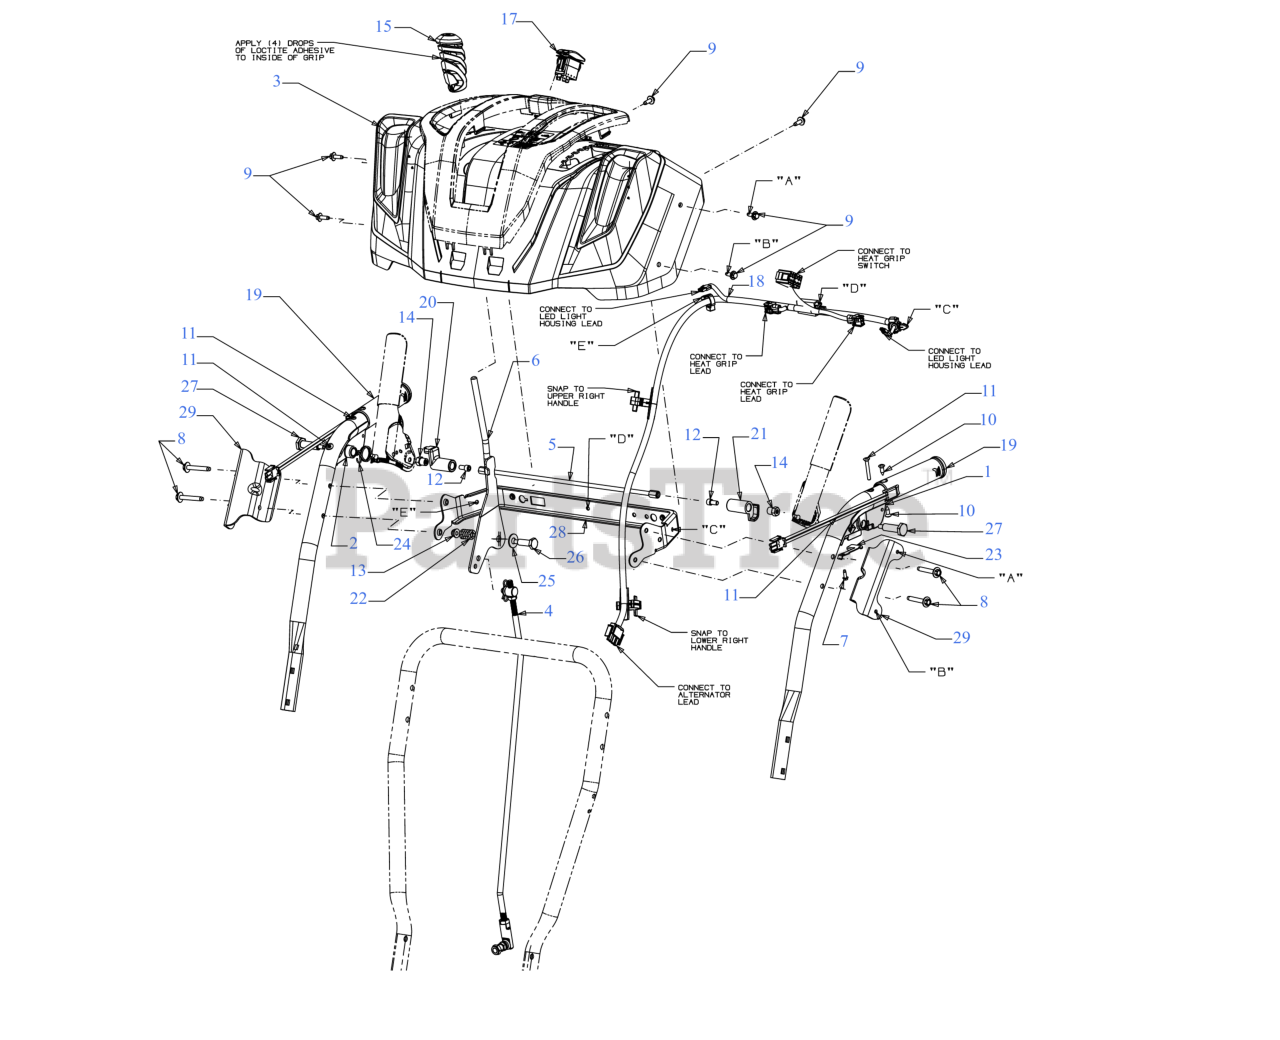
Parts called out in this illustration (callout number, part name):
1	CLUTCH LOCK HANDLE ASSEMBLY (LH)
2	CLUTCH LOCK HANDLE ASSEMBLY (RH)
4	SHIFT ROD ASSEMBLY
6	SPEED SHIFT CONTROL (POWDER BLACK)
7	SCREW #8-16 x .50
8	SCREW 1/4-20 x 1.625
9	SCREW M6-1 x .625
10	SCREW-AB #12-24 x .625
11	SCREW #10-24 x 1.375
12	SCREW 1/4-20 x .50
13	FLANGE LOCK NUT
14	HEX NUT W/PATCH
15	PTO HANDLE GRIP .355 ID
17	HEATED GRIP SWITCH
18	HARNESS (TWO HEADLIGHT)
19	HEATED GRIP
21	CLUTCH LOCK CAM
22	COMPRESSION SPRING
23	CLUTCH SPRING
24	TORSION SPRING
25	FLAT WASHER .40X.88X.060
26	SHOULDER SCREW
27	SHOULDER SCREW .437 x 1.345 1/4-20
28	HANDLE SUPPORT BRACKET (POWDER BLACK)
29	HANDLE PANEL BRACKET (POWDER BLACK)
